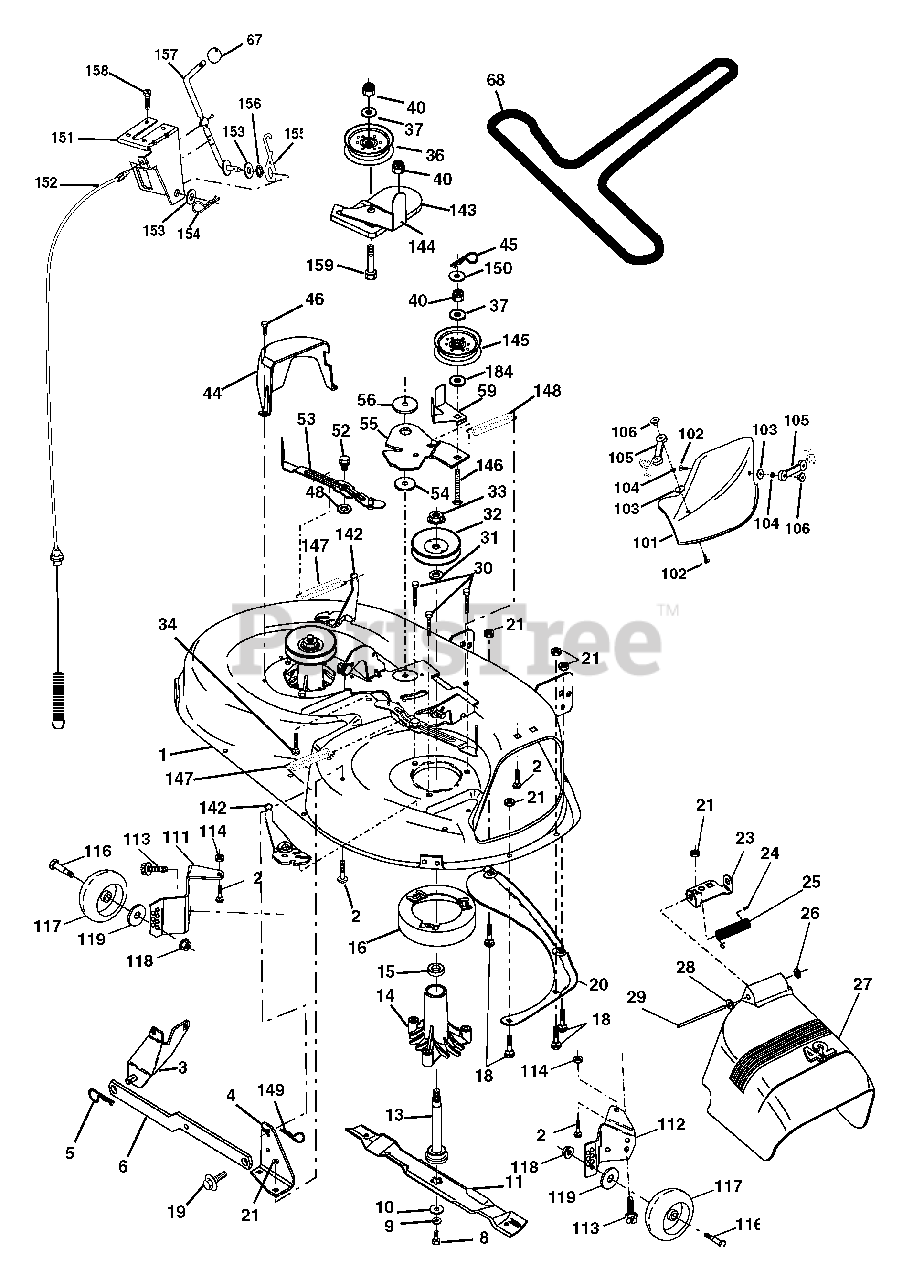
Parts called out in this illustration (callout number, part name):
1	Mower Deck Assembly, 42"
2	Bolt
3	Bracket Assembly,Sway Bar, Front
4	Bracket Sway Bar 38/42" eck
5	Retainer Spring
6	Bar Sway Deck
8	Bolt, Hex 3/8-24 x 1.25 Gr. 8
9	Washer, Lock
10	Washer, Hardened
11	Blade, 42" Mulching Std
11	Blade, 42" Mulching Premium
11	Blade, 42" Hi-Lift
13	Shaft Assembly, Mandrel, Vented
14	Housing, Mandrel, Vented
15	Bearing, Ball, Mandrel
16	Stripper, Mower Deck
18	Bolt, Carriage 5/16-18 x 5/8
19	Bolt, Shoulder
20	Baffle, Vortex
21	Nut Crownlock 5/16-18 Unc
23	Bracket, Deflector
24	Cap, Sleeve
25	Spring, Torsion, Deflector
26	Nut, Push
27	Shield, Deflector
28	Washer 11/32 x 5/8 x 16 Ga.
29	Rod, Hinge
30	Screw Thdrol DOD PT Hex
31	Washer, Spacer
32	Pulley, Mandrel
33	Nut, Toplock, Flanged
34	Bolt
36	Pulley, Idler, Flat
37	Washer 13/32 x 13/16 x 16 Ga.
40	Nut Crownlock 3/8-16 Unc
44	Guard, Mandrel, L.H.
45	Retainer
46	Screw, Thd. Roll 1/4-20 x 5/8
48	Washer, Hardened
52	Bolt, Shoulder 5/16-18 Unc
53	Arm Assembly, Pad, Brake
54	Washer, Hardened
55	Arm, Idler
56	Spacer, Retainer
59	Guard, TUV Idler
67	Knob
68	V-Belt
101	Mulcher Cover
102	Screw Pan Hd Phillips 10-24 x 5/8
103	Washer #10
104	Washer, Lock #10
105	Latch Assembly, Bagger
106	Nut, Weld
111	Bracket Wheel Guage LH
112	Bracket Wheel Guage RH
113	Screw 3/8-16 x .625
114	Nut Keps 5/16-18 Unc
115	Bolt 5/16-18 x 5/8
142	Arm Spring Brake Mower
143	Bracket Arm Idler 42"
144	Keeper Belt 42" Clutch Cable
145	Pulley Idler Flat
146	Bolt Carriage Idler
147	Spring Extension
148	Spring Return Idler
149	Retainer Spring Yellow Zinc
150	Washer 9/32 x 3/4 x 16 Ga.
151	Bracket Clutch
152	Cable Clutch 42 In
153	Washer Flat 3/8" Type B
154	Spring Retainer
155	Spring Retention Lever
156	Spacer
157	Rod Clutch
158	Screw Hex Thd Cut 1/4-20 x 5/8
159	Bolt Rdhd Sqn 3/8-16 Unc x 1-3/4
184	Washer 13/32 x 7/8 x 10 Ga.
